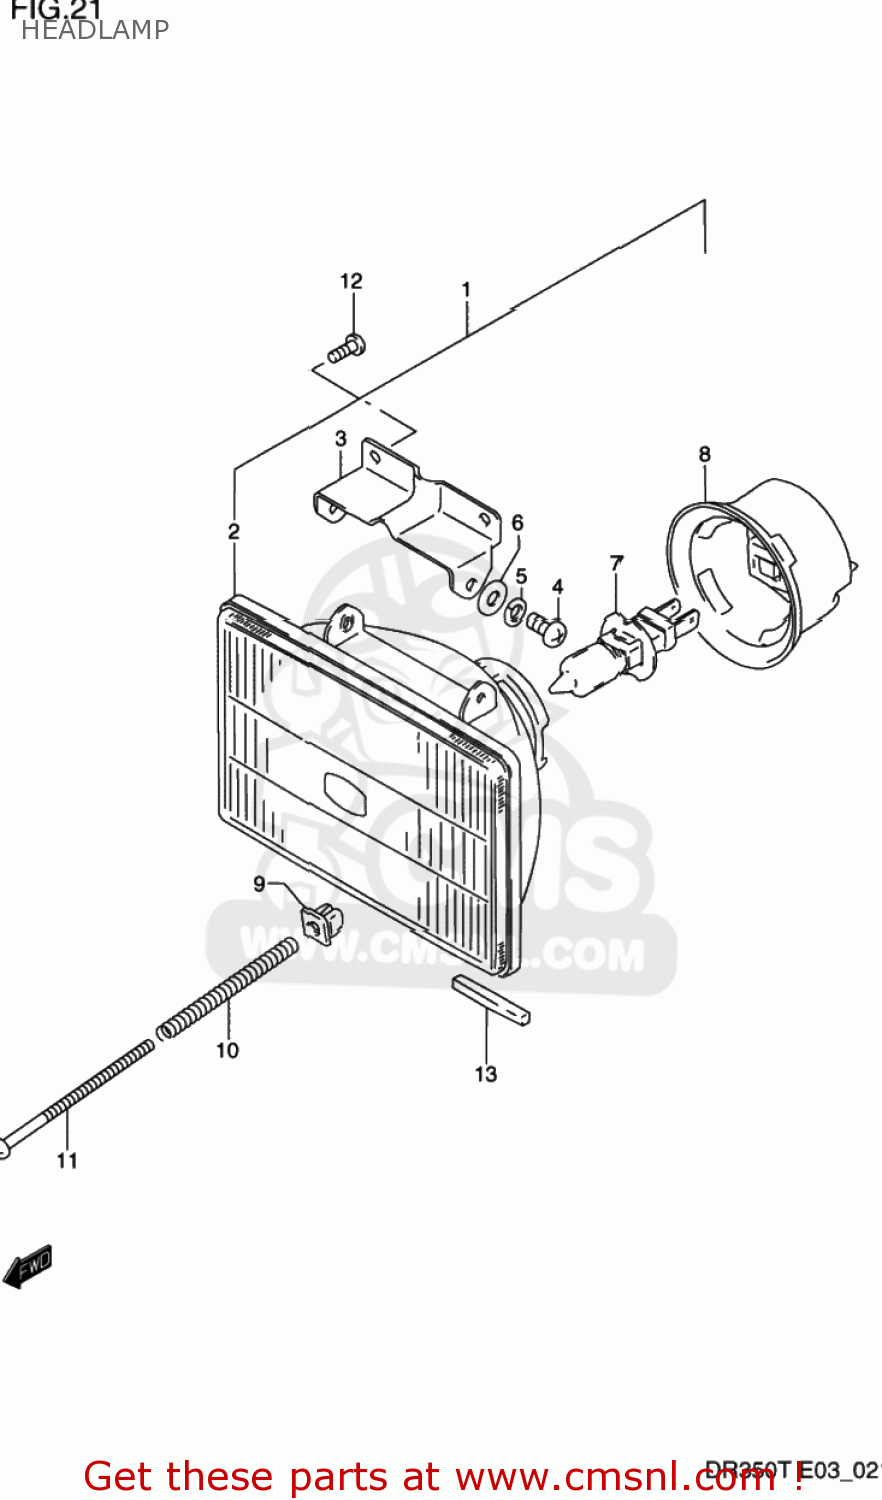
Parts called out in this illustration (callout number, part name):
1	HEADLAMP ASSY
2	UNIT,LAMP
3	BRACKET,LAMP
4	SCREW
5	LOCK WASHER
6	WASHER
7	BULB(12V55W)
8	COVER,SOCKET
9	NUT,ADJUSTING
10	SPRING,HEAD LAMP ADJUSTER
11	SCREW(4X45)
12	SCREW
13	PROTECTOR,BATTERY
